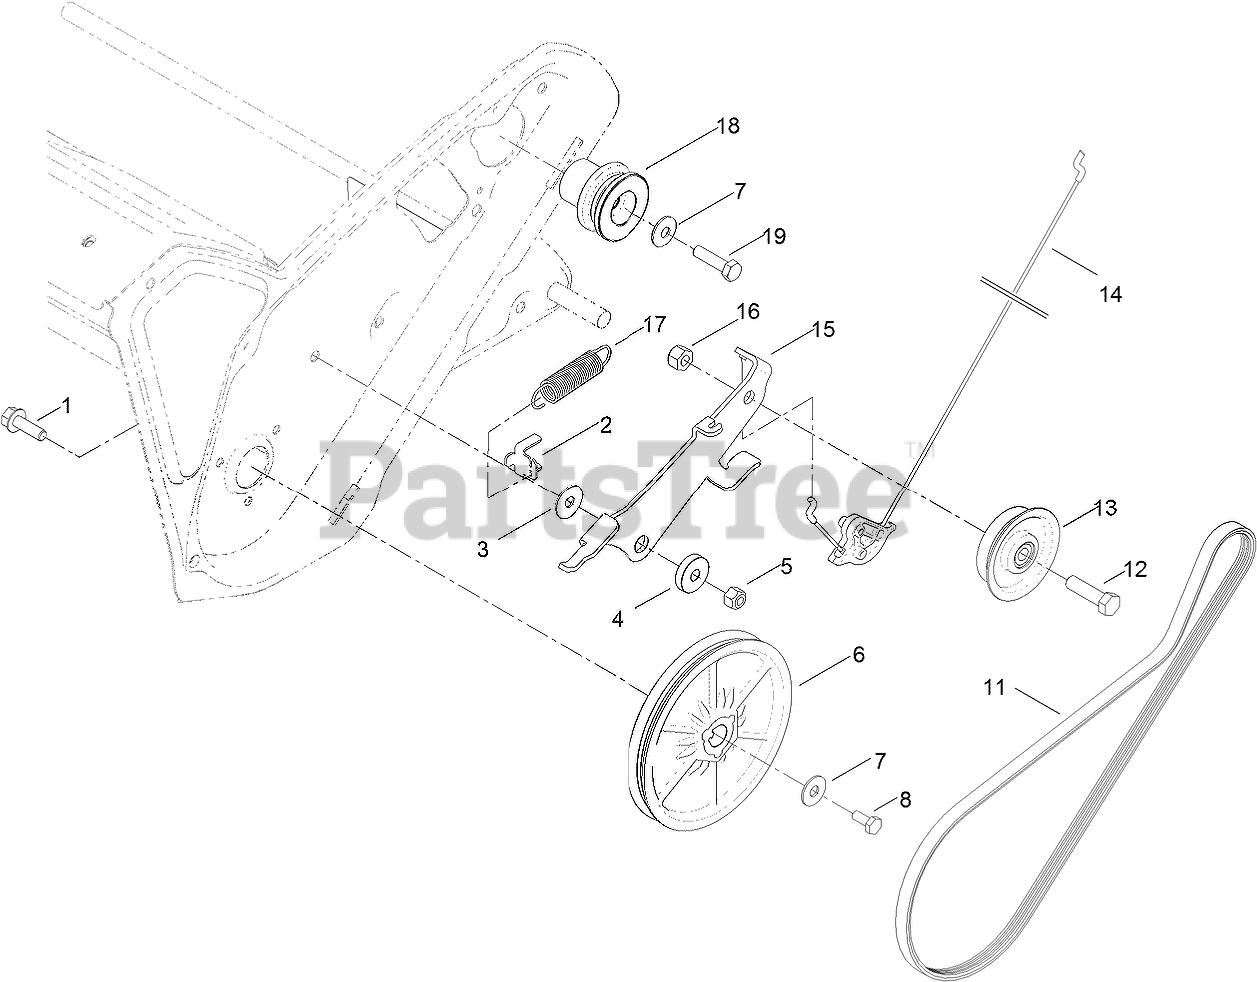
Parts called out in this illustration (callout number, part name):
1	SCREW-HHF
2	CLIP-SPRING, BRAKE
3	WASHER
4	BUSHING-PIVOT
5	NUT-LOCK, NI
6	PULLEY
7	WASHER-BELLEVILLE
8	SCREW-HH
11	BELT-DRIVE
12	SCREW-HH
13	PULLEY-IDLER
14	CABLE-CLUTCH
15	ARM-IDLER
16	NUT-LOCK, CONE
17	SPRING-EXTENSION
18	PULLEY-ENGINE
19	SCREW-HH
